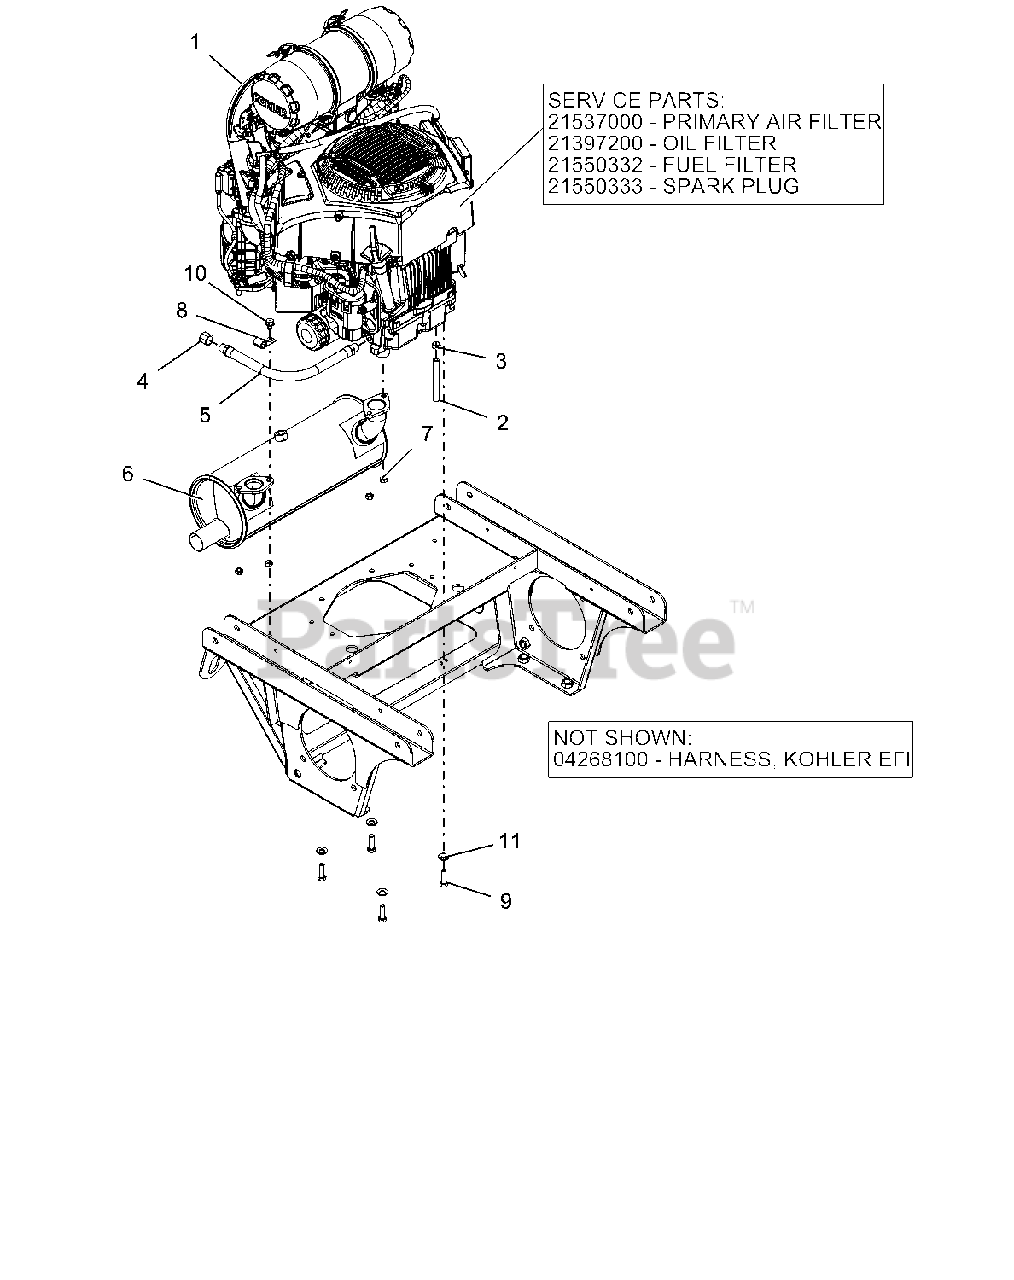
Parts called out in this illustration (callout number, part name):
1	FILTER, OIL - KOH CV20
1	ELEMENT, OUTER PRIMARY
1	ENGINE, KOHLER EFI
1	FILTER, FUEL-KOHLER EFI
1	PLUG, SPARK-KOHLER EFI
2	HOSE, .25 LOW-PERM BULK GAS
3	CLAMP, FUEL LINE
4	PIPE CAP 3/8 NPT FEMALE
5	HOSE,HYD .38-14-0K M6N0-M6N0
6	MUFFLER, KOHLER EFI
7	NUT-LK-TOP M8-1.25 YWZC
9	BLT-HEX.38-16X1.25 G5YZ NYTORQ
10	SCR-TAP .38-16X.50 HWH TR YWZ
11	WASHER, 3/8" SPRING DISC
